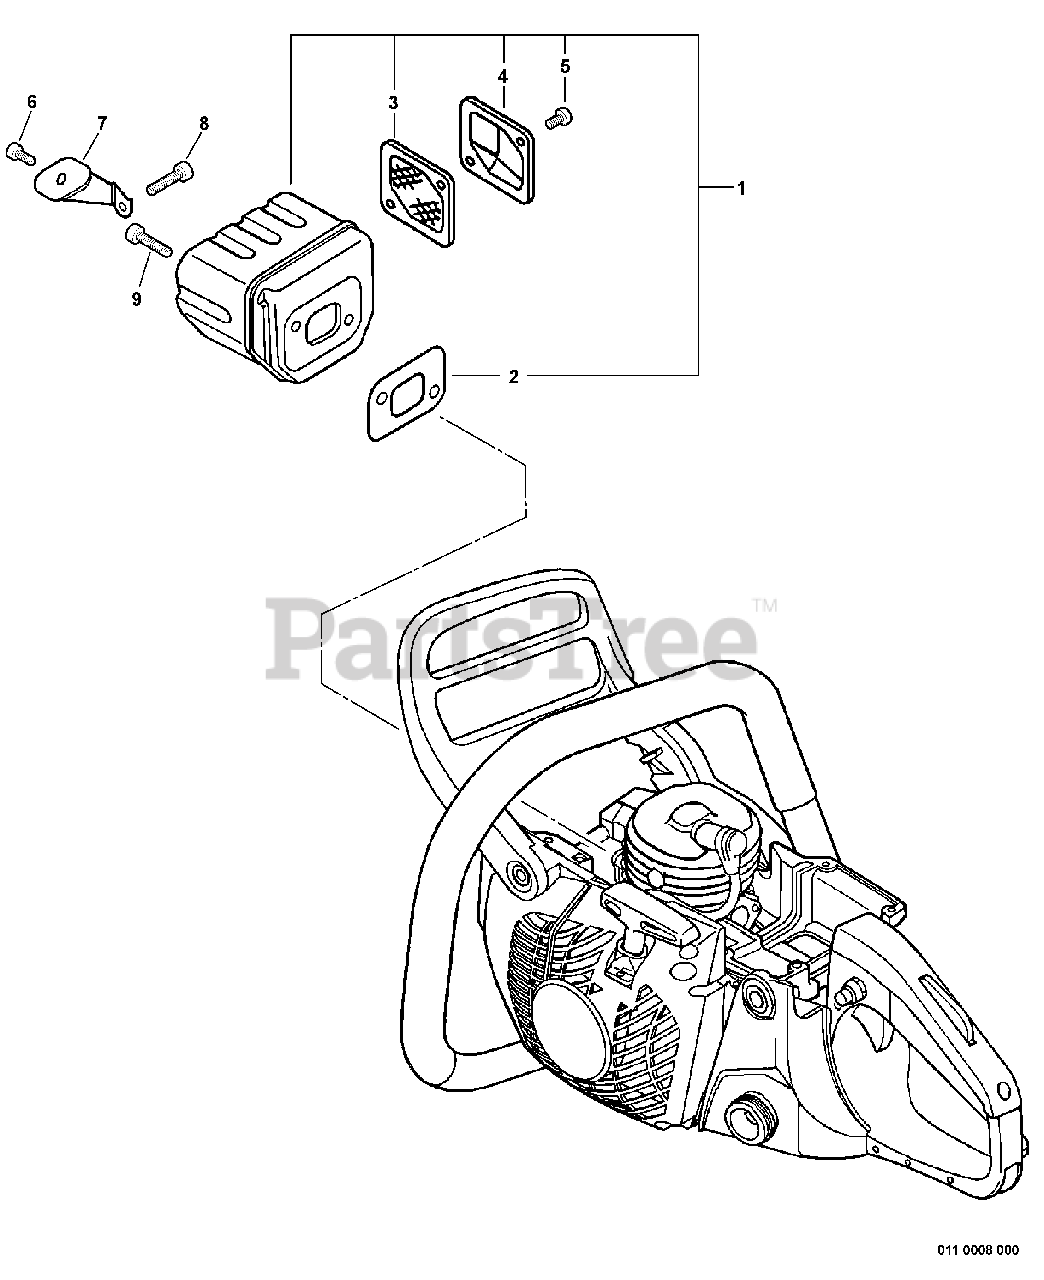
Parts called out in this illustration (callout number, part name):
1	MUFFLER ASSY
2	GASKET, MUFFLER
3	SCREEN, SPARK ARRESTER
4	COVER, MUFFLER
5	SCREW TAPPING 4×8
6	BOLT 6×8
7	BRACKET, MUFFLER
8	SCREW 6×14
9	BOLT 5×14
